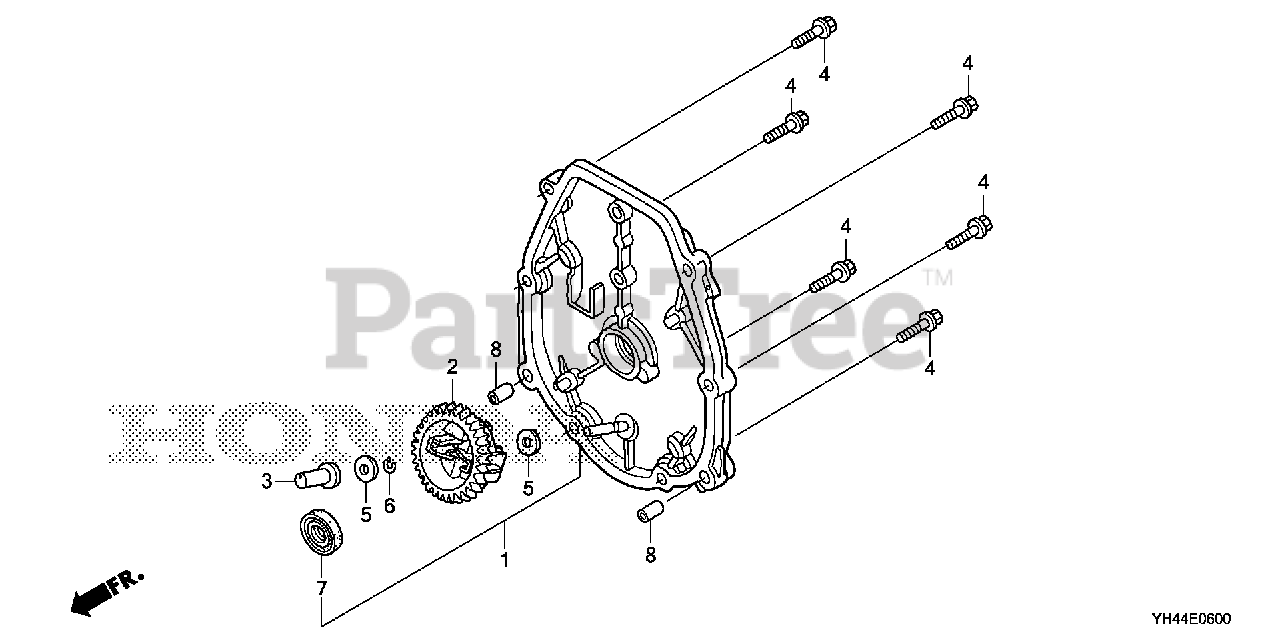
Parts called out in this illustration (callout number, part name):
1	COVER, CRANKCASE SIDE
2	GOVERNOR ASSY.
3	SLIDER, GOVERNOR
4	BOLT, FLANGE (5X23)
5	WASHER (4.2X13)
6	CLIP, GOVERNOR HOLDER
7	OIL SEAL (17X27X5) (KOYO)
8	PIN A, DOWEL (6X10)
